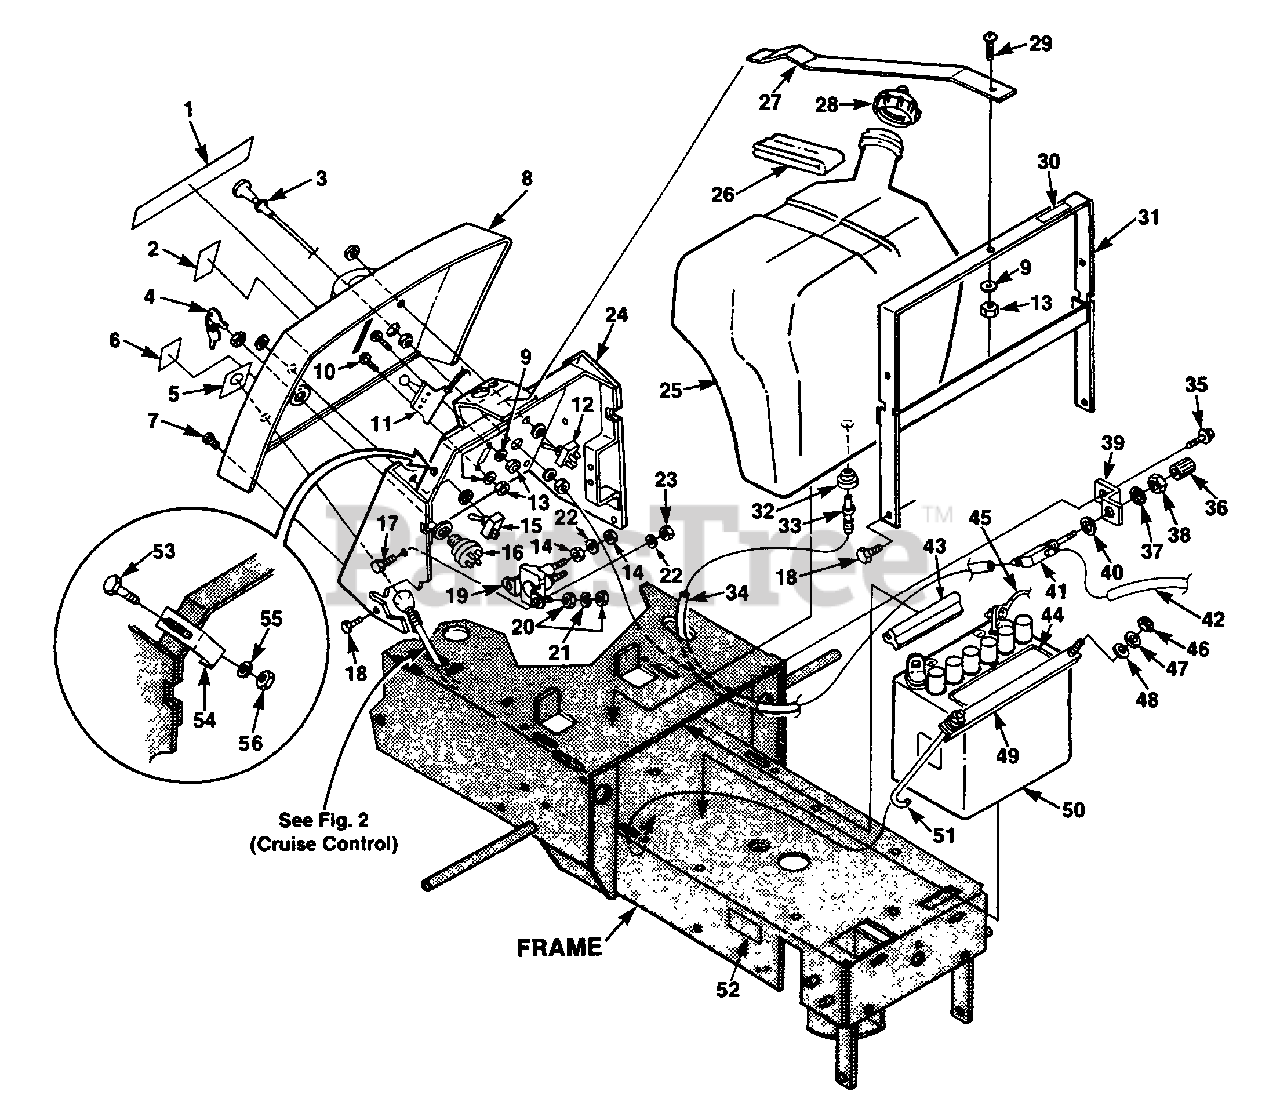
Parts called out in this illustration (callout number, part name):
1	DECAL- Start-Stop
2	DECAL- Throttle
3	CONTROL- Choke
4	KEY- Ignition
5	DECAL- Cruise Control
6	DECAL- Warning
7	SCREW- (#10 x 3/4")
8	PANEL- Dash
9	WASHER- Flat (1/4")
10	SCREW- (#10-24 x 3/8")
11	CONTROL- Throttle
12	SWITCH- P.T.O.
13	NUT- Hex Lock (10-24)
14	NUT- Hex (1/4-20)
16	SWITCH- Key
17	SCREW- (1/4-20 x 1/2")
18	BOLT- Steering Support
20	NUT- Mach (8-32)
21	WASHER- Lock (#8)
22	WASHER- Lock (1/4-20)
23	NUT- Hex (1/4-20)
24	CONTROL TOWER
25	TANK- Gas
26	PAD- Rubber
27	STRAP- Upper
28	CAP- Fuel
29	SCREW- (10-24 x 1/2")
30	DECAL- Gasohol
31	BRACKET- Gas Tank
32	BUSHING- Gas Tank
33	FITTING- Tank
34	TUBE- Fuel (7-50")
35	SCREW- (1/4-14 x 3/4")
36	KNOB- Shut Off
37	WASHER- Lock
38	NUT- R.H. (7/16-20)
39	BRACKET- Fuel Valve
40	WASHER
42	TUBE- Fuel (28.00") (YT-15)
43	CUSHION- Rubber
44	DECAL- Battery
45	CABLE- Battery
46	NUT
47	WASHER- (#10)
49	STRAP- Battery
51	BOLT- Battery
52	DECAL- Warning
53	SCREW- (5/16-18 x 5/8")
55	WASHER- Int Tooth (5/16")
56	NUT- Hex (5/16-18)
